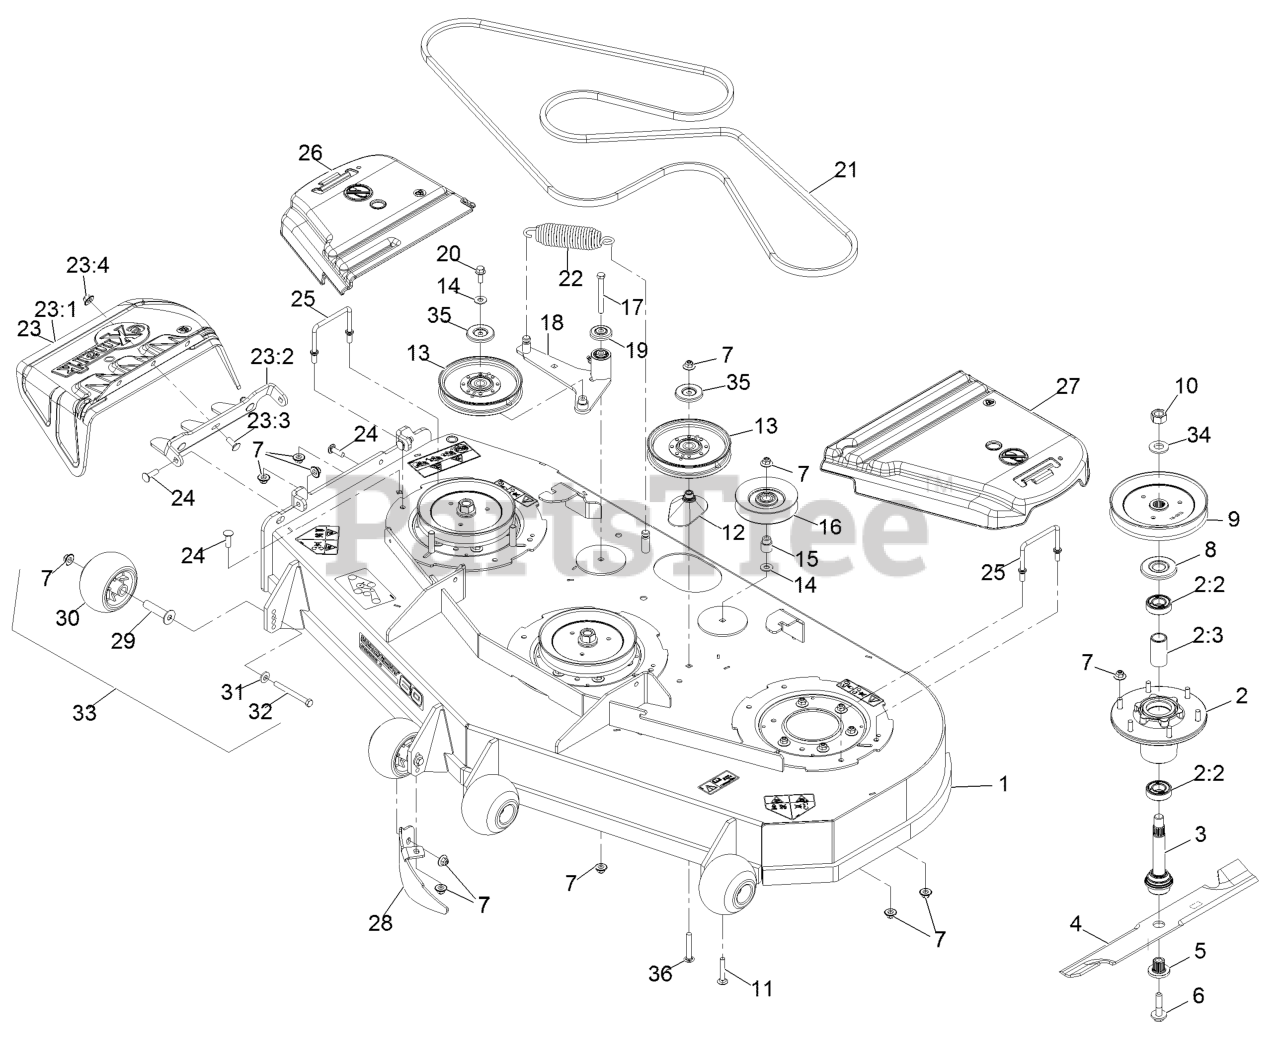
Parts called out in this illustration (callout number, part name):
1	DECK ASM-604
2	ASM-CUTTER HSG WITH BEARINGS
2:2	BEARING-BALL
2:3	SPACER-BEARING
3	ASM-SPINDLE AND SEAL
4	Blade-Extreme 2, 20.50"
5	BUSHING,SPLINED
6	SCREW,SEMS 1/2-20 X 2.19
7	Nut-Nyloc 3/8-16 Flg
8	GUARD,BEARING TOP .989
9	SHEAVE,BLADE DRIVE 7.25
10	NUT-HEX
11	Bolt-Carriage 3/8-16 X 2 1/4
12	SPACER-PULLEY
13	IDLER-PULLEY
14	WASHER-FLAT
15	BUSHING-IDLER
16	PULLEY-IDLER
17	SCREW-CARR
18	DECK IDLER ASM
19	GUARD-TOP
20	SCREW-HHF
21	V-BELT
22	SPRING-EXTENSION
23	ASM,DISCHARGE CHUTE
23:1	CHUTE,DISCHARGE
23:2	BRACKET,DISCHARGE CHUTE
23:3	SCREW-CARR
23:4	Nut-Nyloc 3/8-16 Flg
24	Bolt-Carriage 3/8-16 X 1 1/4
25	WIREFORM-COVER
26	COVER-BELT, RH
27	COVER-BELT, LH
28	DOGLEG - LZ60
29	AXLE, ROLLER
30	ROLLER-SCALP, ANTI
31	WASHER-BELLEVILLE
32	SCREW-HH 3/8-16 X 3 3/4 GR 8
33	KIT, ANTI-SCALP ROLLER
35	SHIELD-DUST
36	SCREW-CARR
